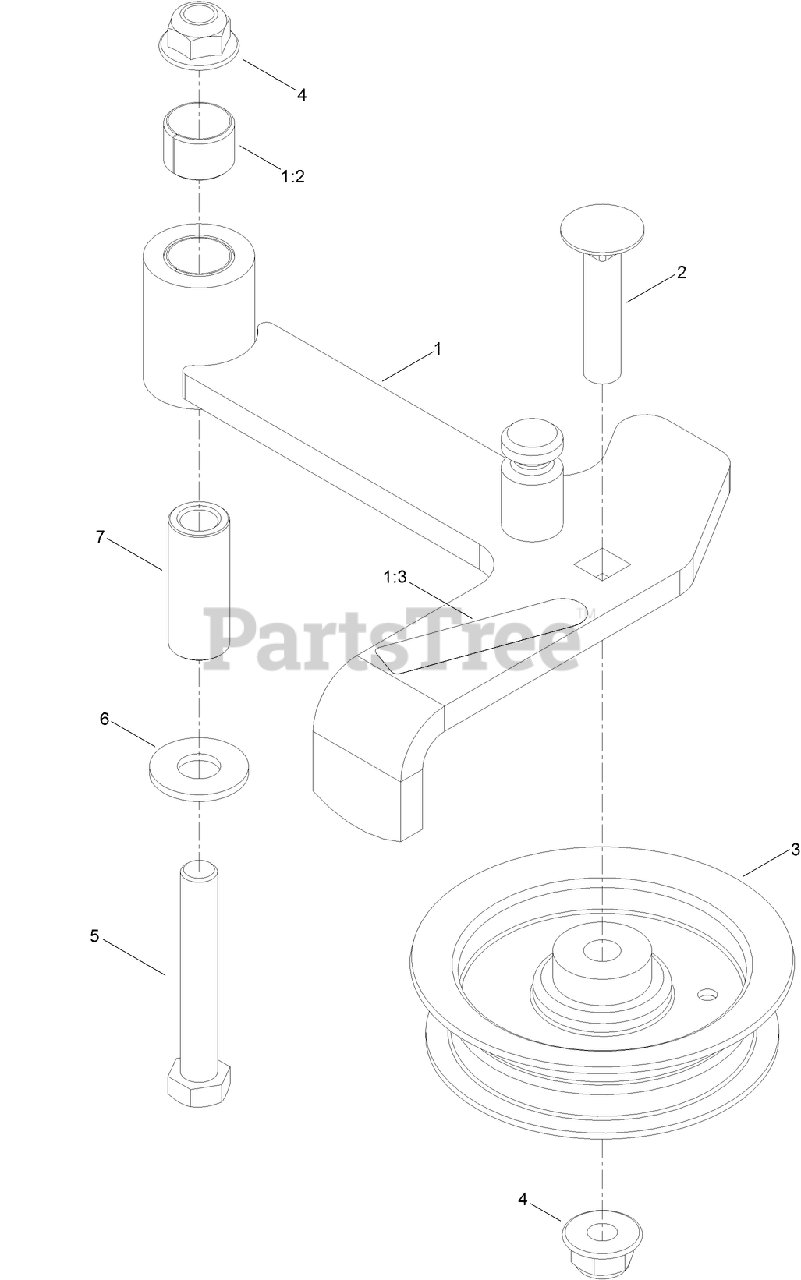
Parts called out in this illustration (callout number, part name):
1	IDLER ARM WITH BUSHING ASM
1:2	BUSHING
1:3	DECAL-WARNING
2	SCREW-CARR
3	IDLER-FLAT
4	NUT-HF, NI
5	SCREW-HH
6	WASHER-FLAT
7	BUSHING
